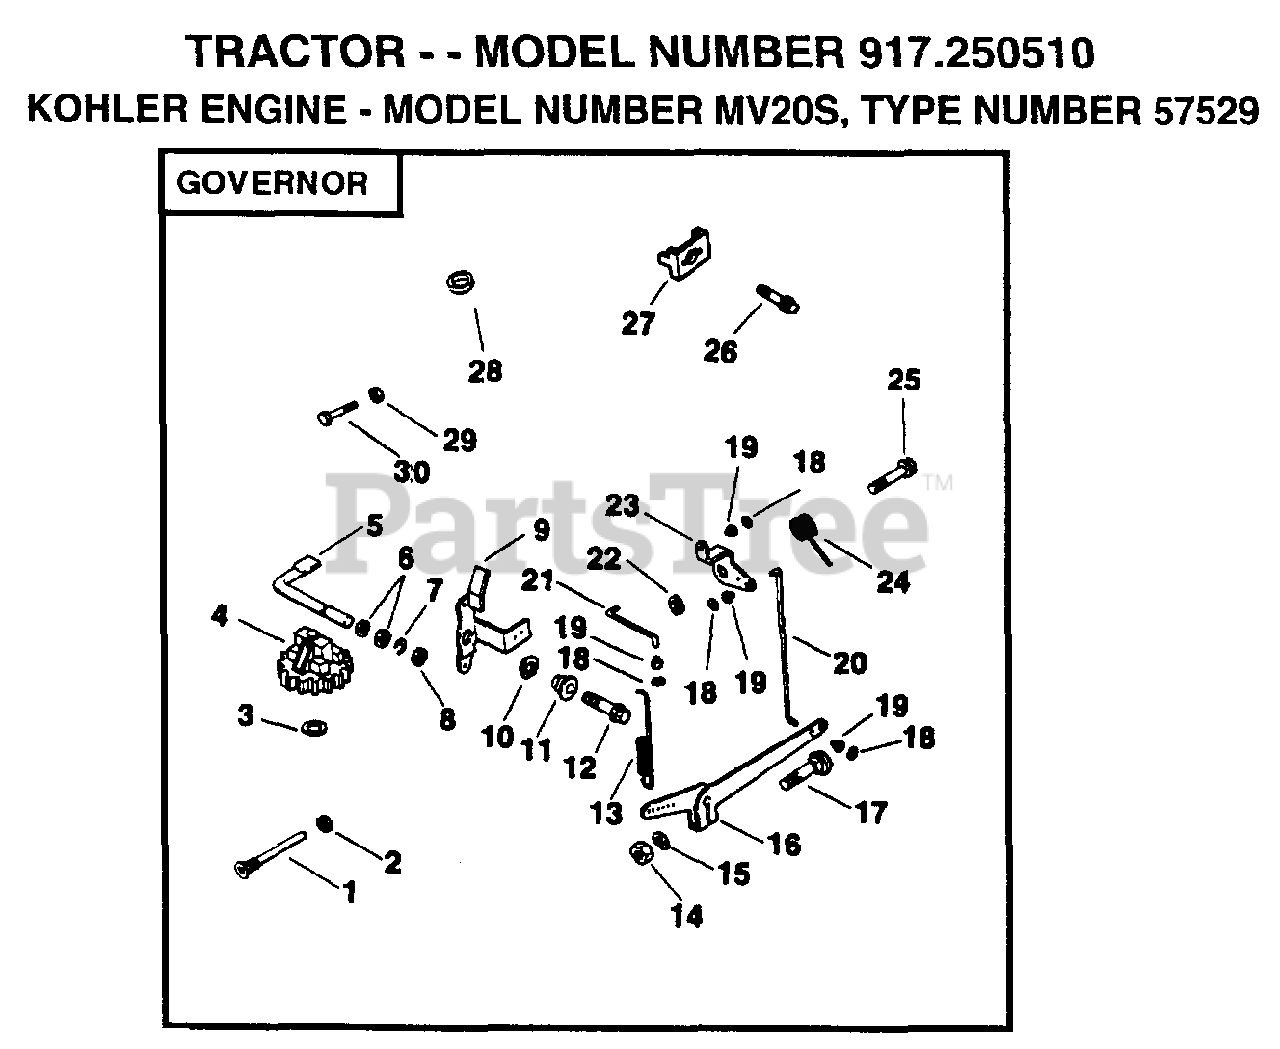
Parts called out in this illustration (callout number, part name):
1	PIN
2	WASHER
3	WASHER
6	WASHER
7	RETAINER
8	WASHER, PLAIN 1/4
10	WASHER
12	SCREW, 1/4-20 X 1
14	NUT
15	WASHER
22	WASHER, PLAIN 1/4
25	SCREW, HEX 1/4-20 X 5/8
26	CLAMP
27	SCREW
29	NUT, HEX #10-32
